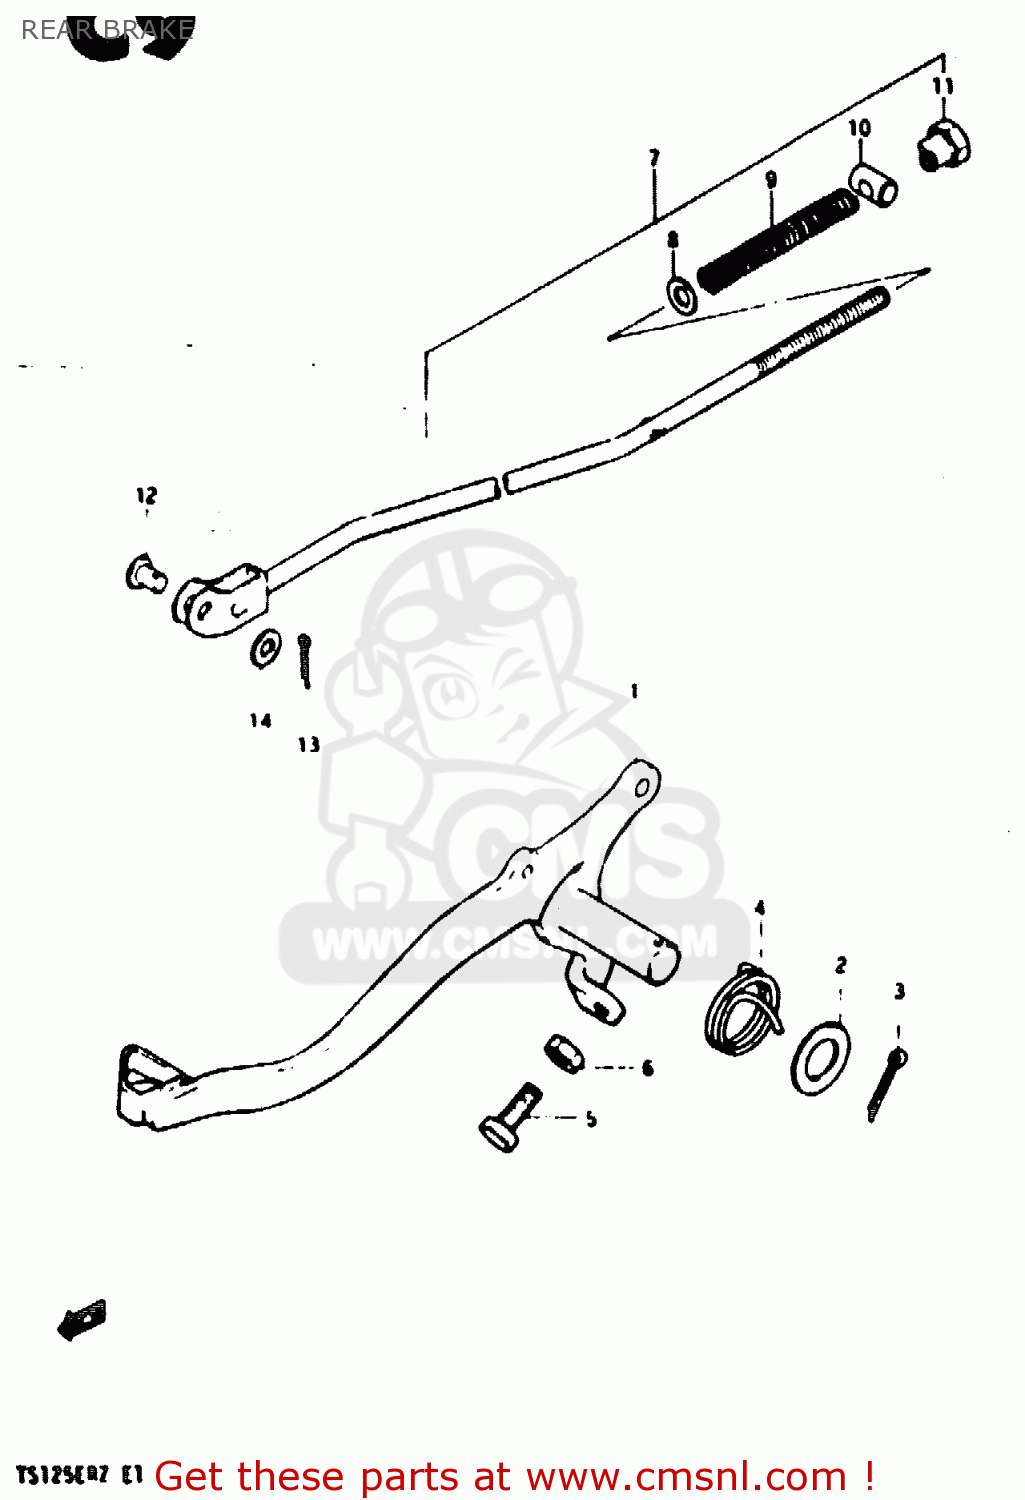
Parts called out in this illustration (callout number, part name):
1	PEDAL,BRAKE
2	WASHER(15.5X26X2.3)
3	COTTER PIN
4	SPRING
5	BOLT(6X23)
6	NUT
7	ROD ASSY,RR BRAKE
8	WASHER
9	SPRING
10	PIN(11X18)
11	NUT
12	PIN
13	PIN 20X20
14	WASHER
